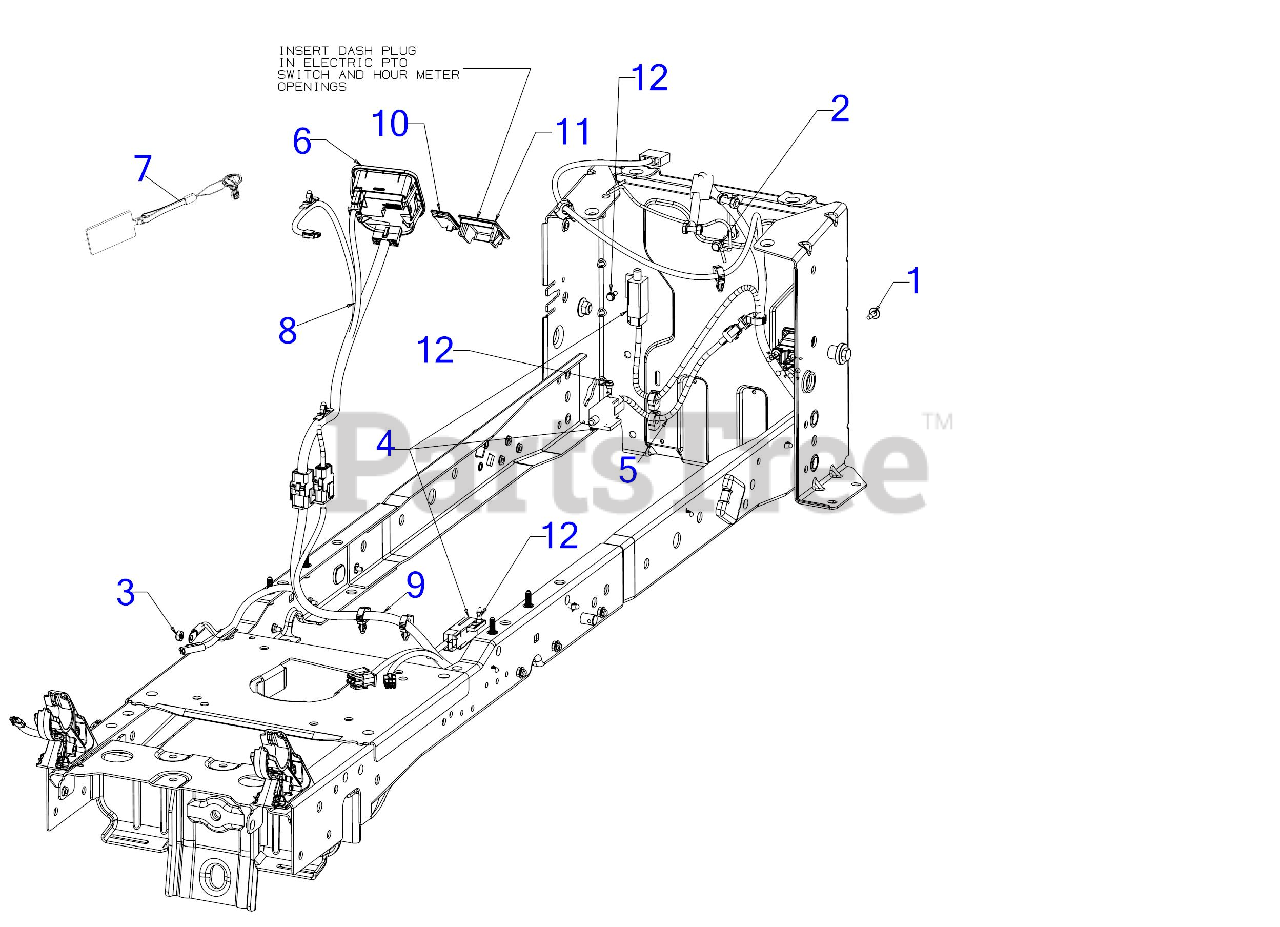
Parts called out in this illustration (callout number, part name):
1	SCREW M6-1 x .625
2	SCREW 1/4-20X.625
3	HEX NUT 1/4-20
4	INTERLOCK SWITCH (NO/NC)
5	REVERSE HARNESS
6	MODULE-PBS/HRMTR/SVC MNDR
7	PBS KEY
8	DASH HARNESS (M-PTO/PBS/EFI/RMC)
9	MAIN HARNESS (M-PTO/PBS/EFI NX15)
11	DASH HOUR METER PLUG
12	SHOULDER SCREW
